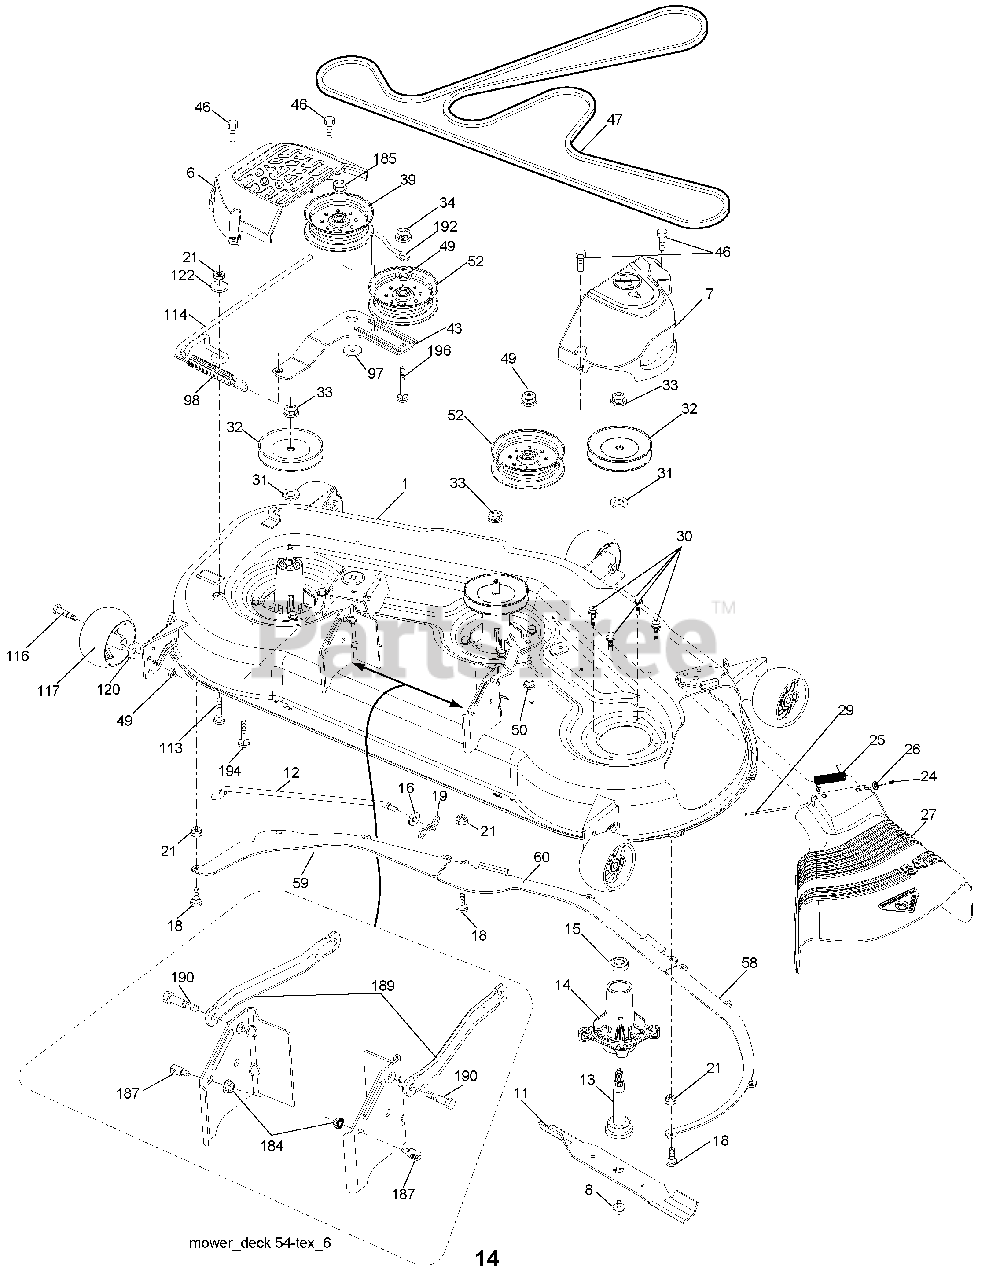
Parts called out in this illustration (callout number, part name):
1	Deck Weldment Mower
6	Cover Mandrel LH
7	Cover Mandrel RH
8	Bolt 7/16 Asm. Blade
11	Blade
11	Blade Mulching
11	Blade Bagging
12	Rod-Anti Sway
13	Shaft Asm. w/Lower Bearing
14	Housing, Mandrel
15	Bearing, Ball, Mandrel
16	Washer 13/32 x 13/16 x 12
18	Bolt 5/16 - 18 x 5/8
19	Pin Cotter 5/16 Bow Tie Lock
21	Nut, Crownlock 5/16-18 unc
24	Cap Sleeve
25	Spring, Torsion
26	Nut, Push
27	Deflector Shield
29	Rod, Hinge
30	Screw, Thdroll Washer Head
31	Washer, Spacer Mower Vented
32	Pulley, Mandrel
33	Nut, Flg. Top Lock
34	Nut Crownlock 3/8-16 unc
39	Pulley, Idler, Stationary
43	Arm, Idler
46	Screw, Thdroll. 1/4-20 x 5/8
47	V-Belt, Mower
49	Nut, Lock Flg. 3/8-16 unc
50	Bolt RDHD SQNK 3/8-16 unc x 2
52	Pulley Idler Clutching
58	Baffle Right
59	Baffle Left
60	Baffle Center
97	Washer Hardened
98	Spring Drive
113	Bolt Rdhd Sqnk 5/16-18 x 3/4
114	Rod Tension Relief
116	Bolt, Shoulder
117	Gauge Wheel
120	Washer 13/32 x 1-1/4 x 12 Ga.
122	Bushing Tension Relief
184	Nut Lock Hex Flange 5/16-18
185	Nut Lock Flange 7/16-14 Gr. 5
187	Stud Fastener w/"D" Anti-Rotation
189	Arm Susp. Mower Rear
190	Bolt Shoulder
192	Keeper Belt Idler
194	Bolt Carr Sqnk 3/8-16 x 2-1/4
196	Bolt Rdhd Sqnk 3/8-16 x 2-1/2 Gr. 5
196	Mandrel Asm. Service
196	Replacement Mower, Complete
